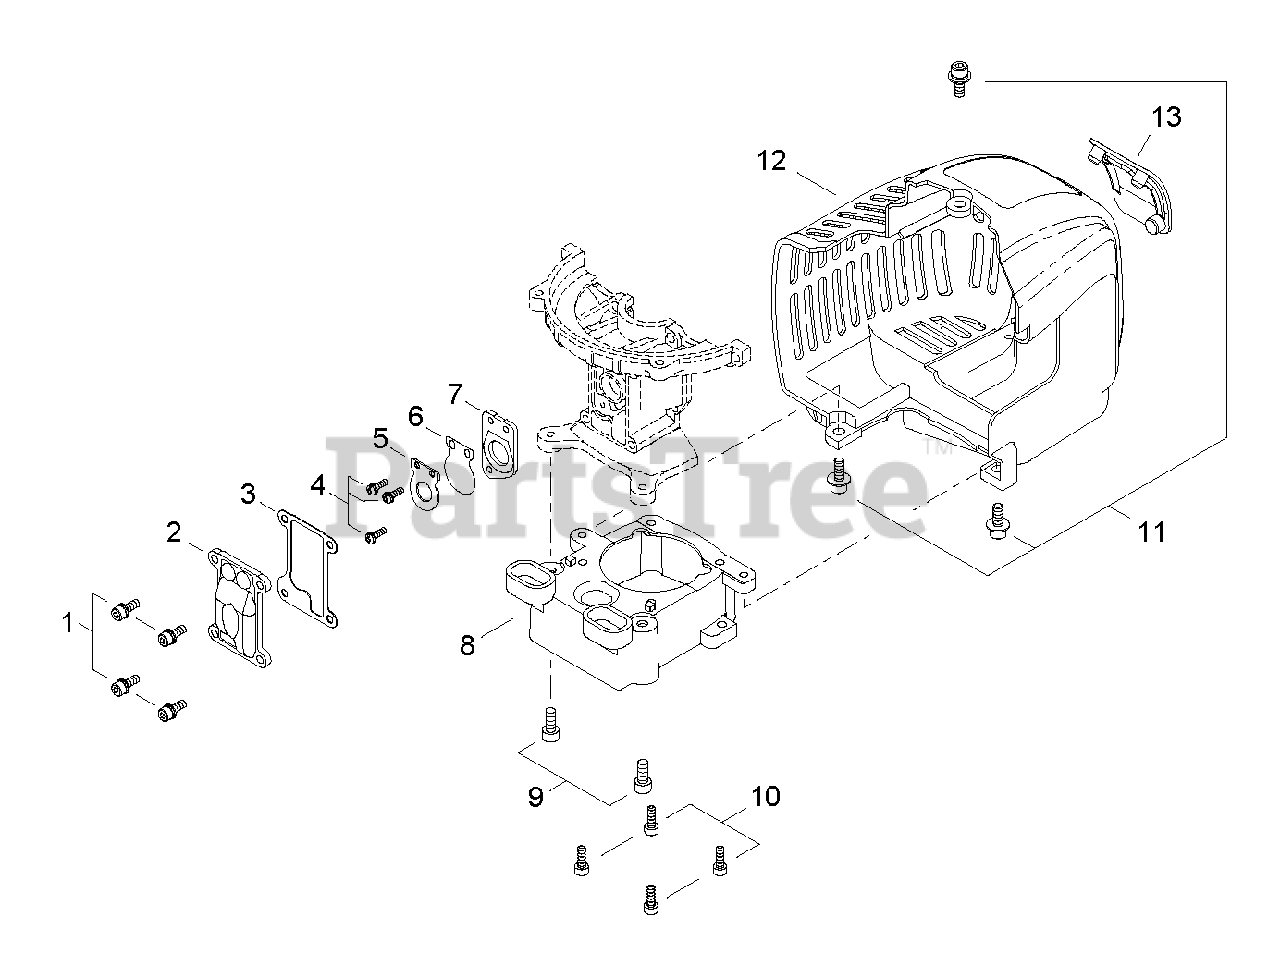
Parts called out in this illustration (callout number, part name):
1	BOLT M4×12
2	COVER, REED VALVE
3	GASKET, REED VALVE
4	SCREW M3×10
5	STOP, REED VALVE
6	VALVE, REED
7	PLATE, REED BACKING
8	ADAPTOR, GEAR CASE
9	BOLT 5×12
10	BOLT 4×12
11	BOLT, ADHESIVE M5×14
12	COVER, ENGINE
13	COVER, SPARK PLUG
